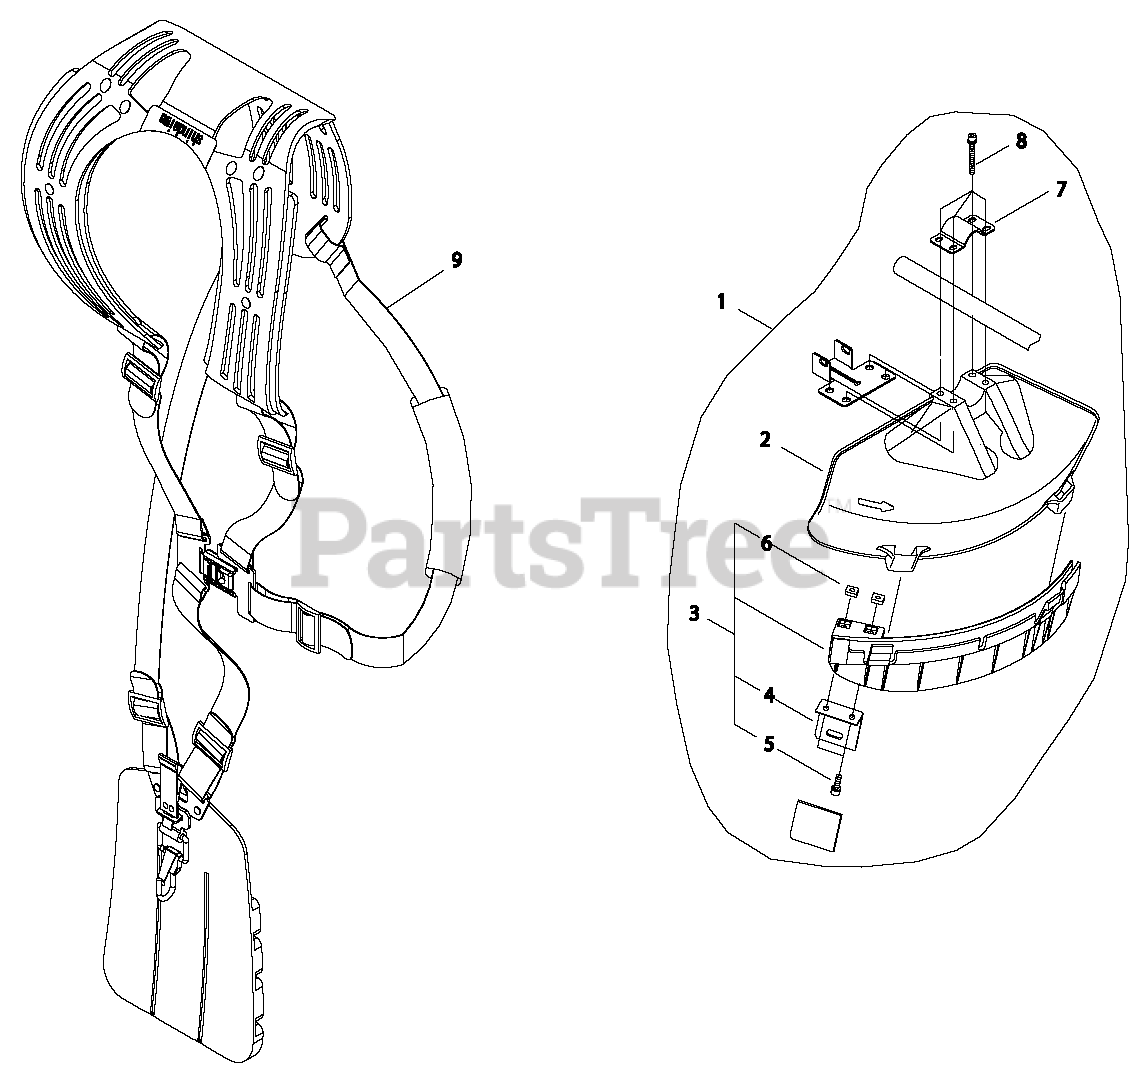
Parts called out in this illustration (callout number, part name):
1	DEBRIS SHIELD KIT
2	SHIELD, DEBRIS PLASTIC
3	DEBRIS SHIELD EXTENSION ASSY
4	CUTTER
5	BOLT M5×16
6	NUT M5
7	CLAMP, UPPER
8	BOLT M5×45
9	HARNESS ASSY
